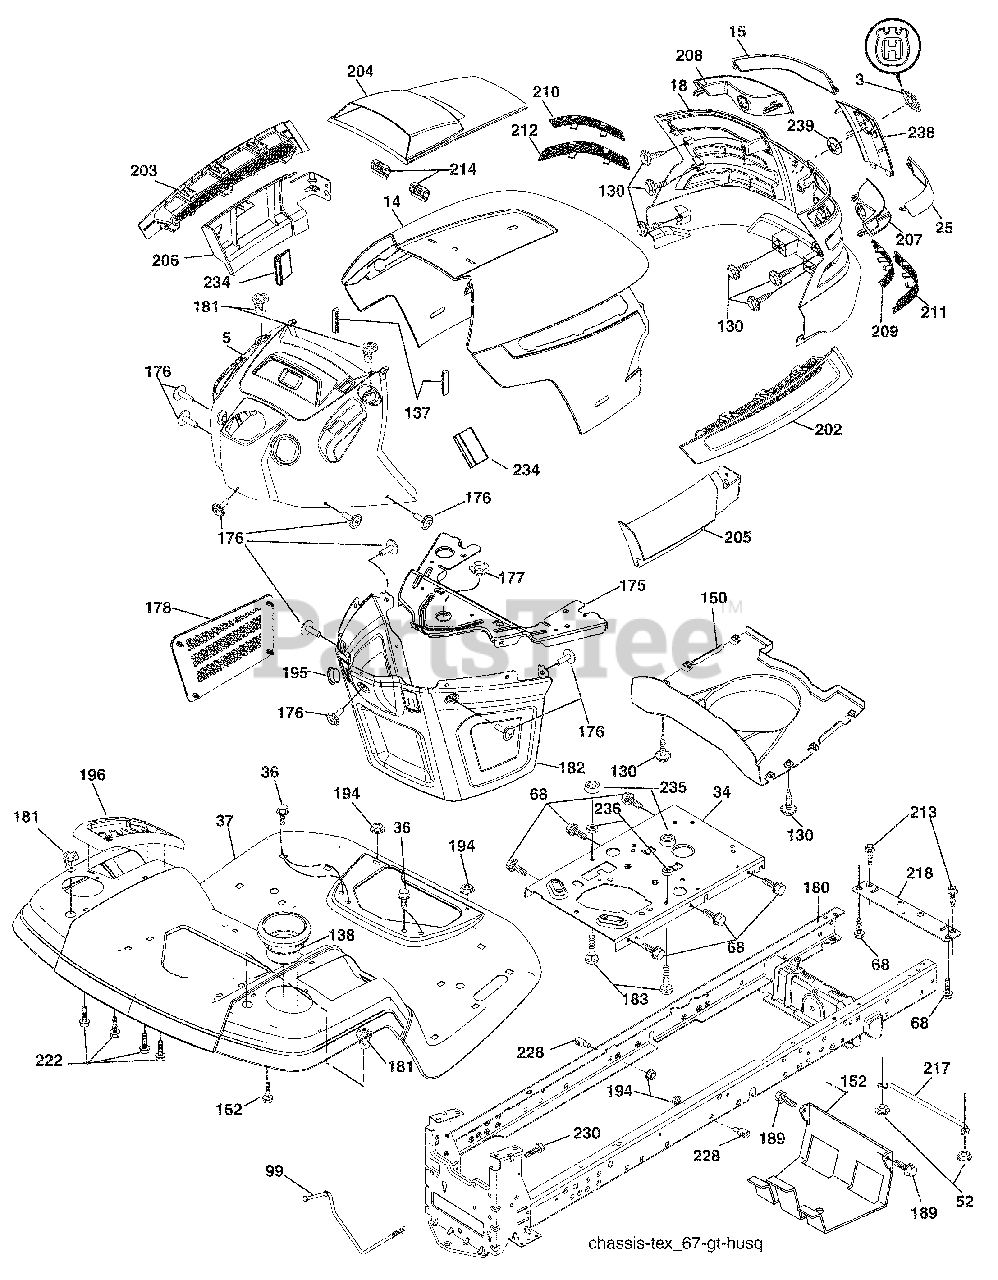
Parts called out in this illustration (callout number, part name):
3	Logo
4	Logo
14	Hood
18	Grille/Lens Asm.
34	Plate Engine
36	Screw 5/16-18 x 3/4
37	Fender
52	Nut Lock 5/16-18
68	Screw Thdrol 5/16-18 x 1/2
99	Rod Asm Bypass
130	Screw 10 x 3/4 Single Lead-Hex
137	Bumper Dash
138	Cupholder
152	Shield Browning
175	Crossmember
176	Screw 10-24 x 5/8
177	Bushing Steering
178	Cargo Net Asm.
180	Chassis
181	Bushing Mtg. Fender Crgo
182	Dash Lower
183	Bolt Fin Hex 5/16-18 unc x 1-1/4
189	Screw 5/16-18 x 3/4
194	Nut Lock Hex Flange 5/16-18
195	Plug Hole Dash Lower
196	Console Asm. Deck Lift
202	Vent Side Hood RH
203	Vent Side Hood LH
204	Vent Top Hood
205	Skirt Hood Side RH
206	Skirt Hood Side LH
209	Insert Hex Top RH
210	Insert Hex Top LH
211	Insert Hex Bottom RH
212	Insert Hex Bottom LH
213	Bolt 5/16-18 x 3/4
214	Clip Retainer Tinner
217	Rod Pivot
218	X-Piece Hood Stop
222	Screw Thdrol 1/4-20 x 5/8
228	Stud Fastner
230	Bolt Shoulder 5/16-18
234	Bumper Hood
235	Spacer Fender
236	Nut Lock 5/16-18 unc
